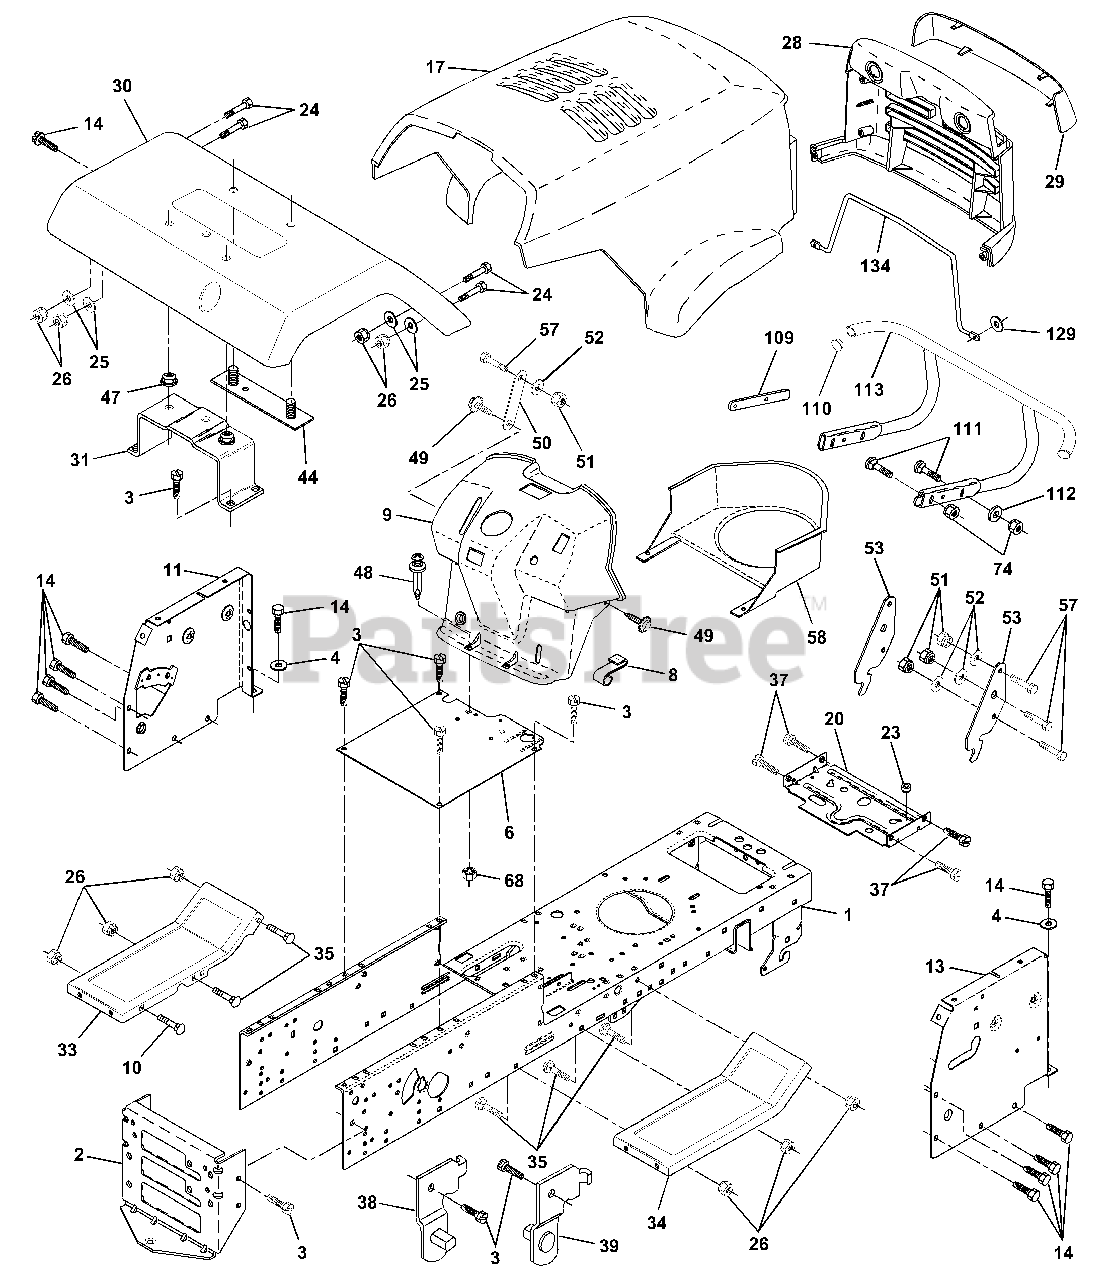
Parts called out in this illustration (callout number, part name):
1	Chassis Weldment 11ga
2	Drawbar, Stretch
3	Screw Thdrol 3/8-16x3/4 Ty-tt
4	Washer 13/32 x 3/4 x 16 Ga.
6	Saddle LT Fender Shift
8	Clip Insulator .406 Mtg Hole
9	Dash P/L w/amm w/HM w/PTO Grey
10	Bolt Carriage 3/8-16 x 1
11	Panel Pnt Dash Lh
13	Panel Dash Rh Asm
14	Screw Thdrol 3/8-16 x 1/2 Ty-tt
17	Hood LT/PL Husqvarna
20	Plate Mtg. Battery Fuel Tank. 95
24	Bolt Fin Hex 3/8-16unc X 1 Gr. 5
25	Washer 13/32 X 13/16 X 12 Ga
26	Nut Lock Hex W/Ins 3/8-16 Unc
28	Grille LT/PL Husqvrna
29	Lens LT/PL Husqvrna
30	Fender YT/GT w/Shift w/Fuel 94
31	Bracket Asm Fender
33	Footrest Pnt Lh LT/YT/GT 95
34	Footrest Pnt Rh LT/YT/GT 95
35	Bolt Rdhd Sht Sqnk 3/8-16 X3/4
37	Screw Thdrol 5/16-18 X 1/2
38	Bracket, Asm. Pivot, L.H., Mower Rear
39	Bracket, Asm. Pivot, R.H., Mower Rear
44	Strap asm Fender
47	Nut, Push Nylon
48	Rivet Push Plate D Plastick Blk
49	Screw Hexwsh. Thdrol 1/4-20 x 3/4
51	Nut Lock Hex W/Ins 1/4-20
52	Washer 9/32 x 7/8 x 16 Ga.
53	Bracket Pnt. Pick off LT/PL Husq.
57	Bolt Hex 1/4-20 x 3/4
58	Air Duct CV18
68	Nut Keps Hex 1/4-20
74	Nut Crownlock 3/8-16 UNC
109	Bracket Extension Bumper
110	Plug Plastic
111	Bolt Carriage 3/8-16 x 1-1/4
112	Washer 13/32 x 13/16 x 16 Ga.
113	Bumper Asm.
129	Washer 9/32 x 5/8 x 16 Ga.
134	Rod Support Hood LT/PL Husq.
